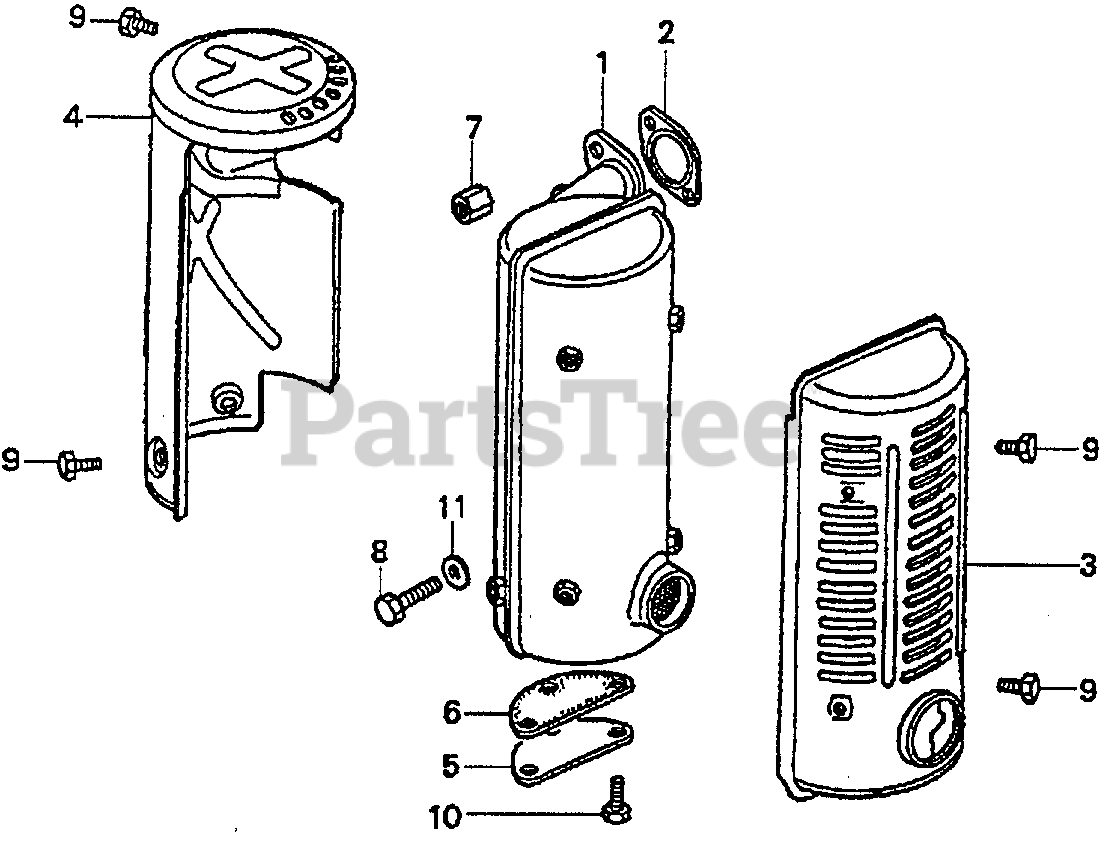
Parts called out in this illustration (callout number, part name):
1	MUFFLER
1	MUFFLER (NOT AVAILABLE)
2	GASKET, MUFFLER (NOT AVAILABLE)
3	PROTECTOR, MUFFLER (NOT AVAILABLE)
4	COVER, RR. MUFFLER
5	LID, MUFFLER (NOT AVAILABLE)
6	GASKET, MUFFLER (NOT AVAILABLE)
7	NUT, HEX. (6MM) (NOT AVAILABLE)
8	BOLT, HEX. (8X18)
9	BOLT, HEX. (6X6)
10	BOLT, HEX. (6X12)
11	WASHER, PLAIN (8MM)
